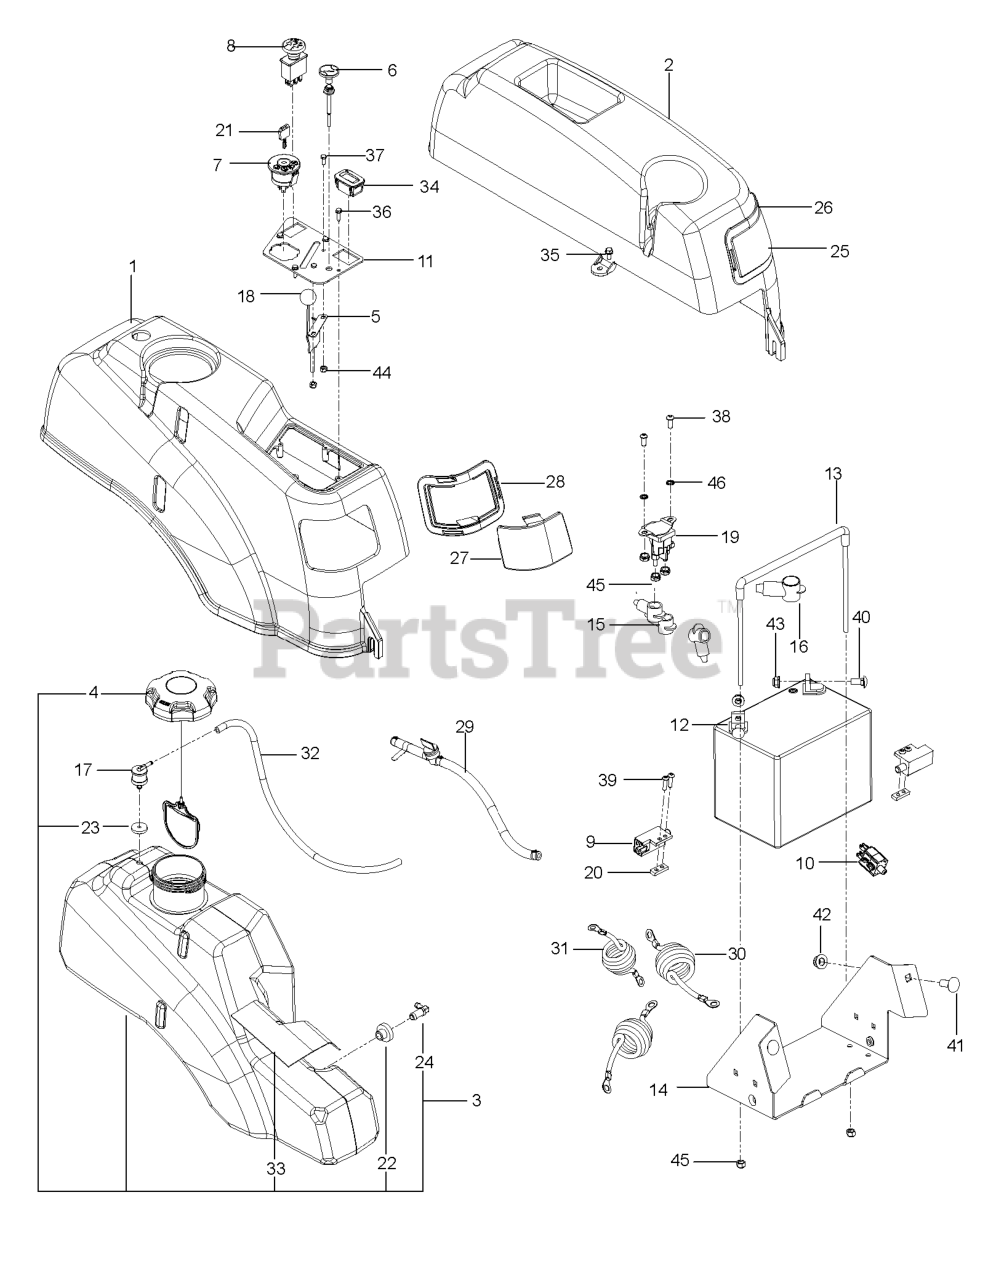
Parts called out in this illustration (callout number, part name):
1	FENDER, RT, GRAY
2	FENDER, LT
3	TANK.FUEL.ASSEMBLY.LARGE
4	CAP, FUEL
5	THROTTLE CABLE
6	CHOKE CABLE
7	RP IGNITION SWITCH
8	RP.SWITCH, BLADE
9	SWITCH INTERLOCKT
10	SWITCH, BRAKE 3P
11	CONSOLE.PLATE.BLACK
12	BATTERY, 12 V 330 AMP
13	BATTERY TIE DOWN ASSEMBLY
14	BOX, BATTERY, BLACK
15	TERMINAL COVER-SM
17	VALVE.FUEL.CHECK
18	KNOB.ROUND.BALL.BLACK
20	TAPPED PLATE
21	KEY
22	RUBBER GROMMET
23	GROMMET, CHECK VALVE
24	STEM, FUEL TANK
25	LENS, COLORED LEFT
26	LEFT HEADLIGHT RIM GREY
27	LENS, COLORED RIGHT
28	RT HEADLIGHT RIM GREY
29	FUEL.HOSE.SHUT.OFF.ASM.10".3"
30	BATTERY CABLE, NEGATIVE
31	CABLE POSITIVE, LONG
32	HOSE, VAPOR 3/16 X 15"
33	SHIELD, HEAT
34	HOUR METER
35	BOLT 1/4-20 X 1/2 HWST
36	HCS #10-24 X 1/2
37	SCR #10-12X3/4 HEX WAS HD ZD
38	SCR 1/4-20 X 5/8 BTN SKT HD ZD
39	SCR #10-24 X .75 SKT HD BLK
40	BOLT 5/16C X 3/4" CARRIAGE
41	RHSNB 3/8C X 1
42	NUT 3/8-16 NYLOC
43	5/16-18 NYLOC FLANGE NUT
44	NUT 10-24 NYLOC
45	NUT.1/4-20.HEX.NYLOC.ZD
46	WASHER 1/4 INT TOOTH
